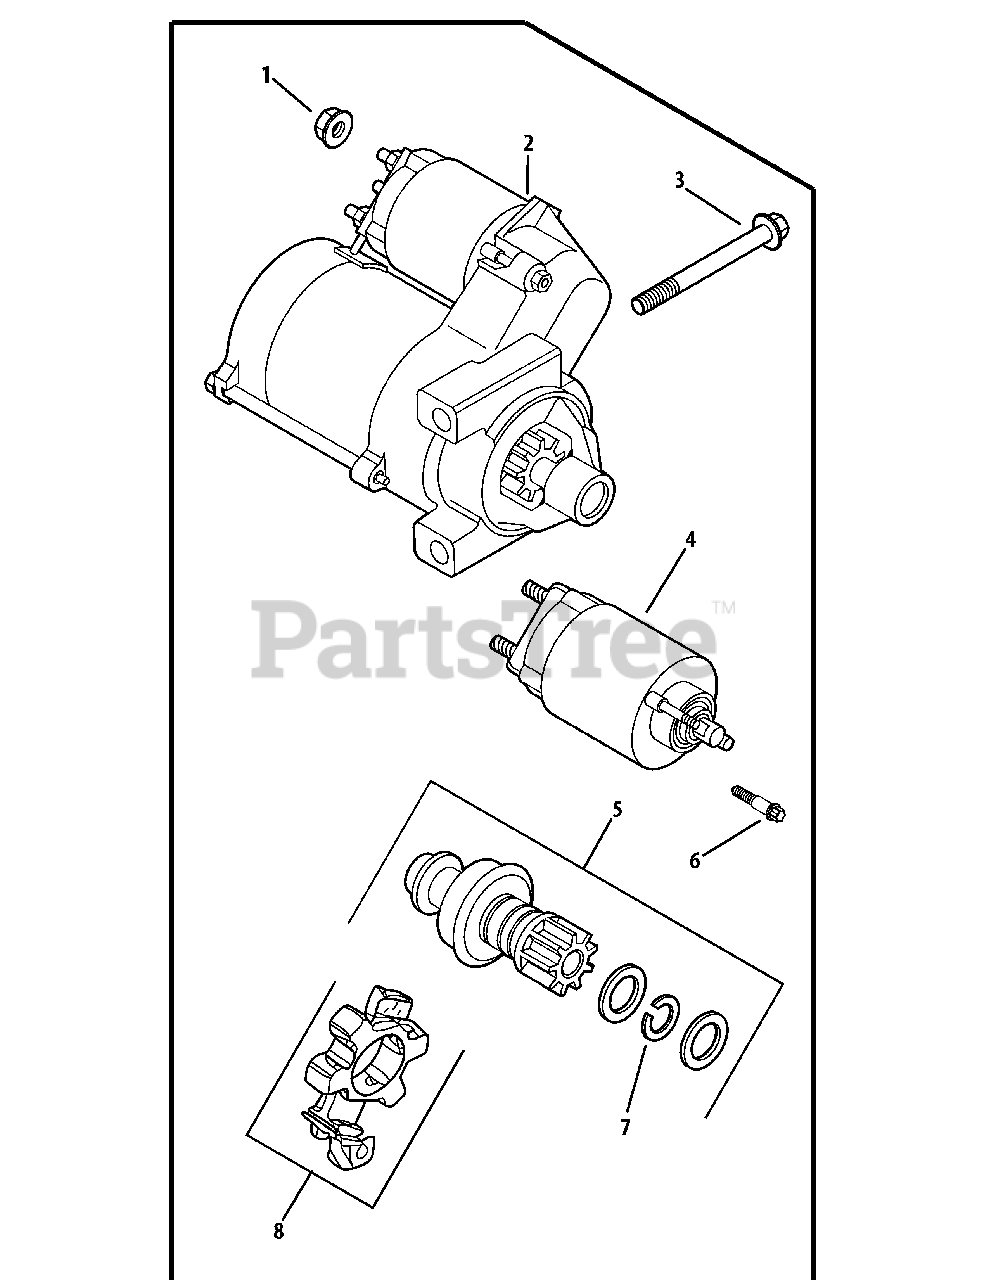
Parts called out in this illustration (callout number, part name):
1	Flange Nut, M8 x 1.25
2	Electric Starter (Solenoid Shift)
3	Flange Screw, M8 x 1.25 x 80
5	Starter Pinion Kit
6	External Torx Head Screw
7	Retaining Ring
8	Brush Holder Kit
